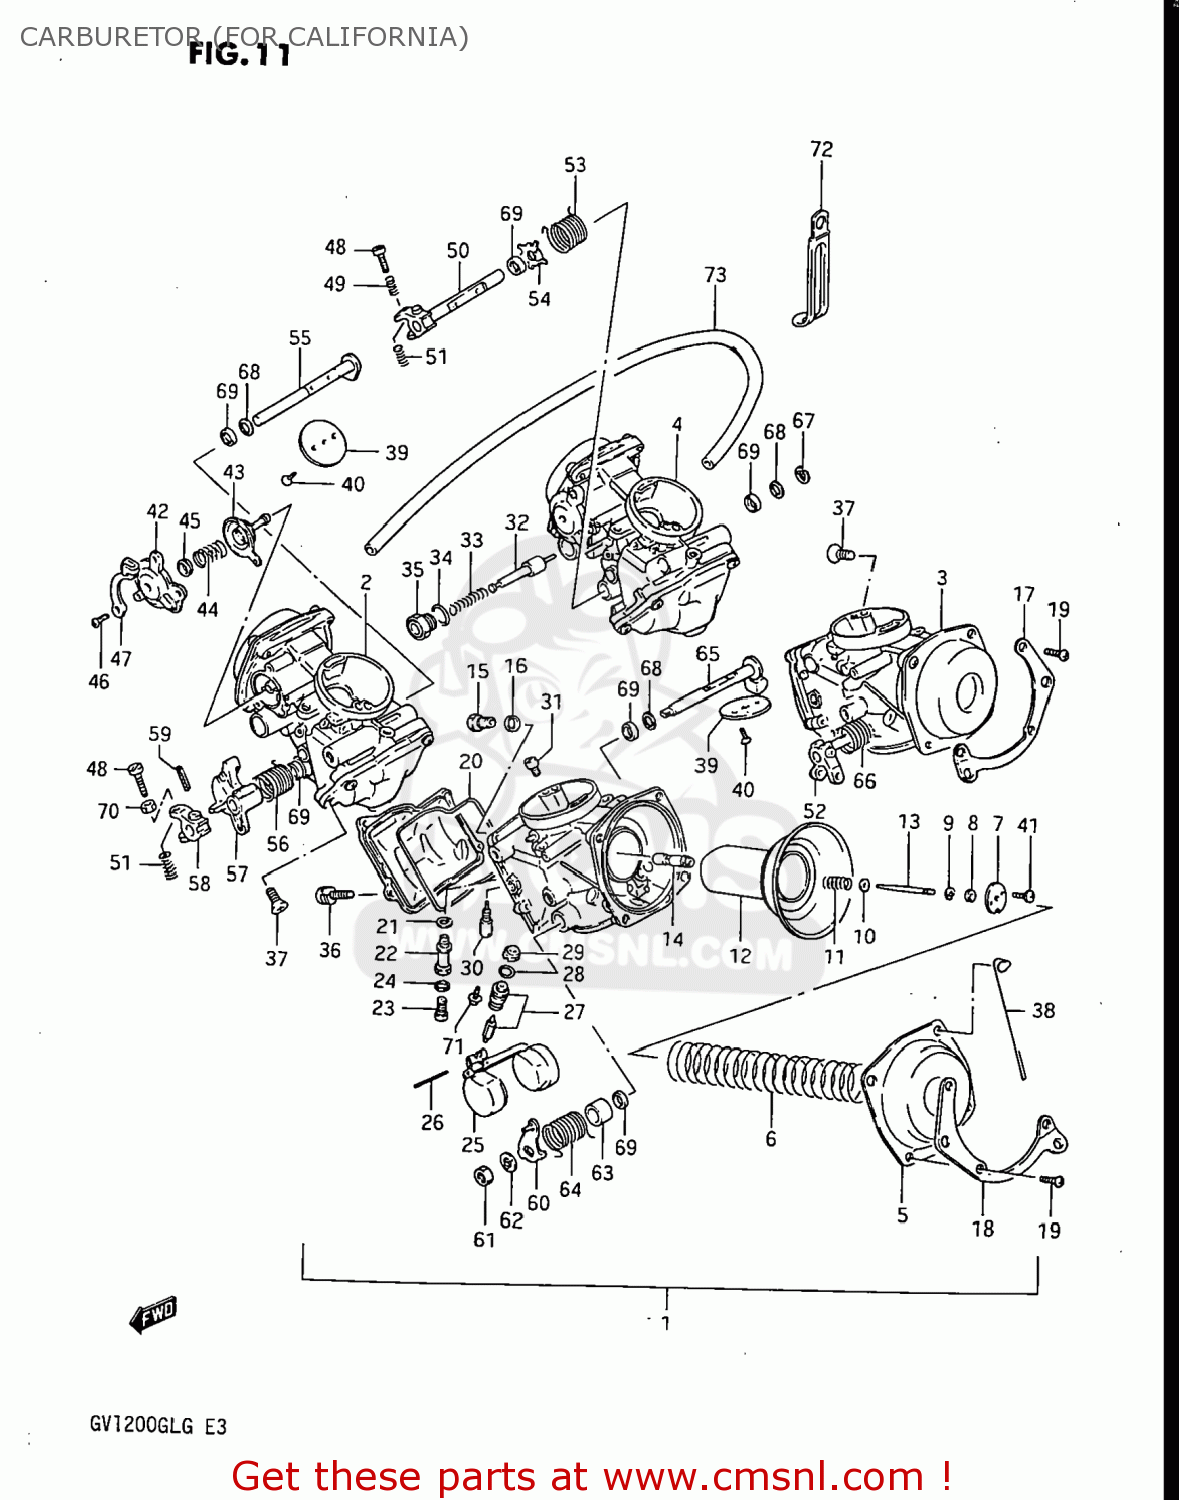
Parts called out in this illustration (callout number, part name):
1	CARBURETOR ASSEMBLY
2	CARBURETOR ASSEMBLY
3	CARBURETOR ASSEMBLY
4	CARBURETOR ASSEMBLY
5	COVER
6	SPRING,DIAPHRAGM
7	PLATE
8	RING
9	CLIP,NEEDLE
10	WASHER
11	SPRING
12	DIAPHRAGM,CARBURETOR
13	NEEDLE JET
14	JET,NEEDLE
15	SCREW
16	WASHER,NEEDLE NOZZLE
17	BRACKET
18	BRACKET
19	SCREW 5X10
20	GASKET,FLOAT CHAMBER
21	GASKET (NAS)
22	HOLDER,MAIN JET
23	JET,MAIN 107,5
24	WASHER
25	FLOAT
26	PIN,FLOAT
27	VALVE ASSEMBLY,NEEDLE
28	O-RING,NEEDLE VALVE
29	FILTER
30	JET,PILOT
31	JET,ENRICH
32	PLUNGER
33	SPRING,STARTER PLUNGER
34	O RING
35	HOLDER,GUIDE
36	SCREW
37	SCREW
38	CLIP
39	VALVE,THROTTLE
40	SCREW
41	SCREW
42	COVER
43	DIAPHRAGM ASSY
44	SPRING
45	PLATE
46	SCREW
47	BRACKET
48	SCREW
49	SPRING
50	SHAFT,THROTTLE
51	SPRING,THROTTLE SCREW
52	SHAFT,THROTTLE
53	SPRING,THROTTLE VALVE
54	PLATE
55	SHAFT,THROTTLE
56	SPRING,THROTTLE VALVE
57	LEVER,THROTTLE
58	LEVER,THROTTLE
59	PIN,THROTTLE SHAFT
60	LEVER,THROTTLE
61	NUT 8MM
62	WASHER
63	RING
64	SPRING,THROTTLE VALVE
65	SHAFT,THROTTLE
66	SPRING,THROTTLE VALVE
67	E RING
68	GASKET,THROTTLE SHAFT (NAS)
69	SEAL,THROTTLE SHAFT
70	NUT
71	SCREW
72	CLAMP L:35
73	HOSE CARBURETOR
